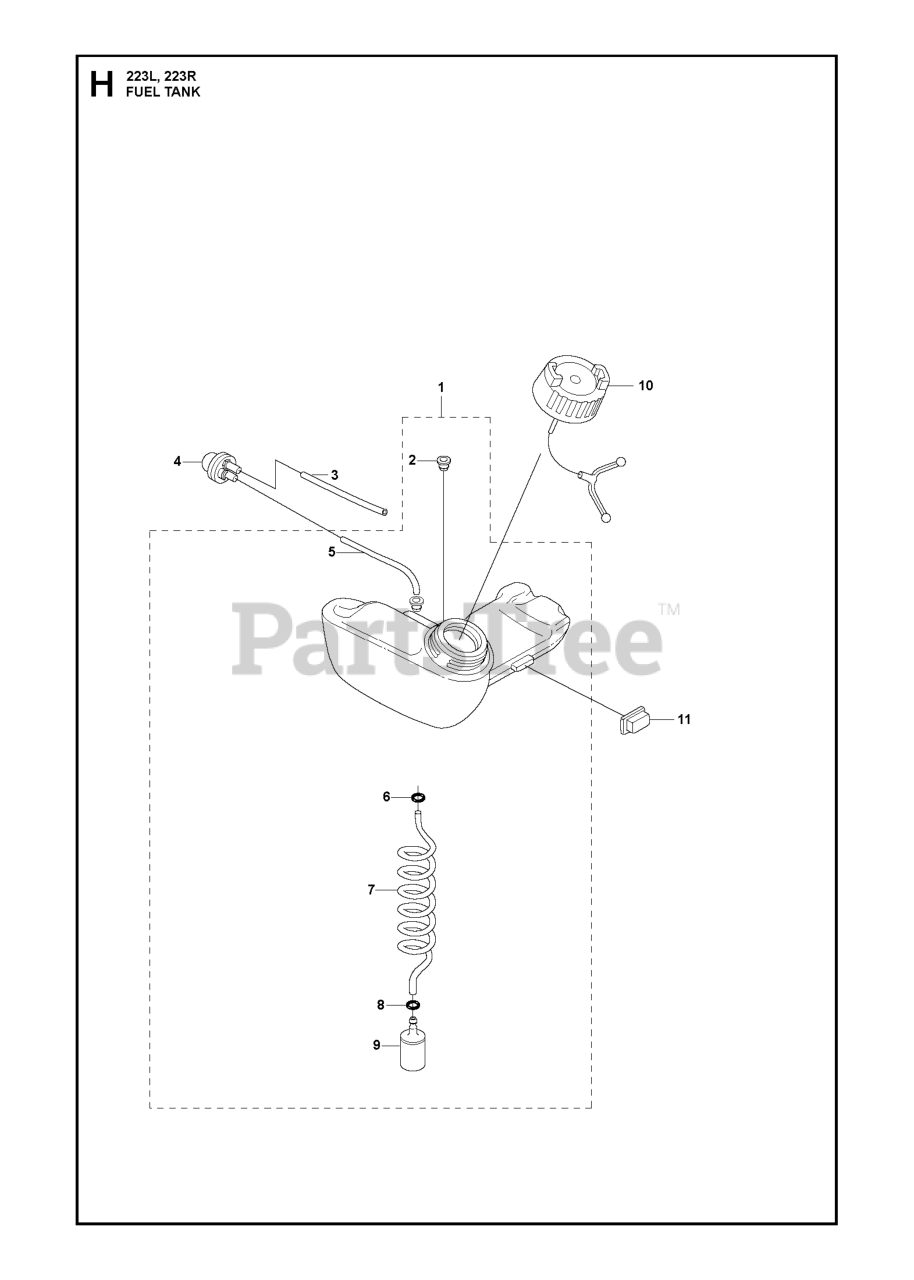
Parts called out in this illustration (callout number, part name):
2	FUEL TANK BUSHING
3	HOSE.FUEL L=102
4	AIR PURGE BUBBLE
5	HOSE.FUEL L=102
7	FUEL HOSE
9	RP FUEL FILTER
10	%FUEL CAP
